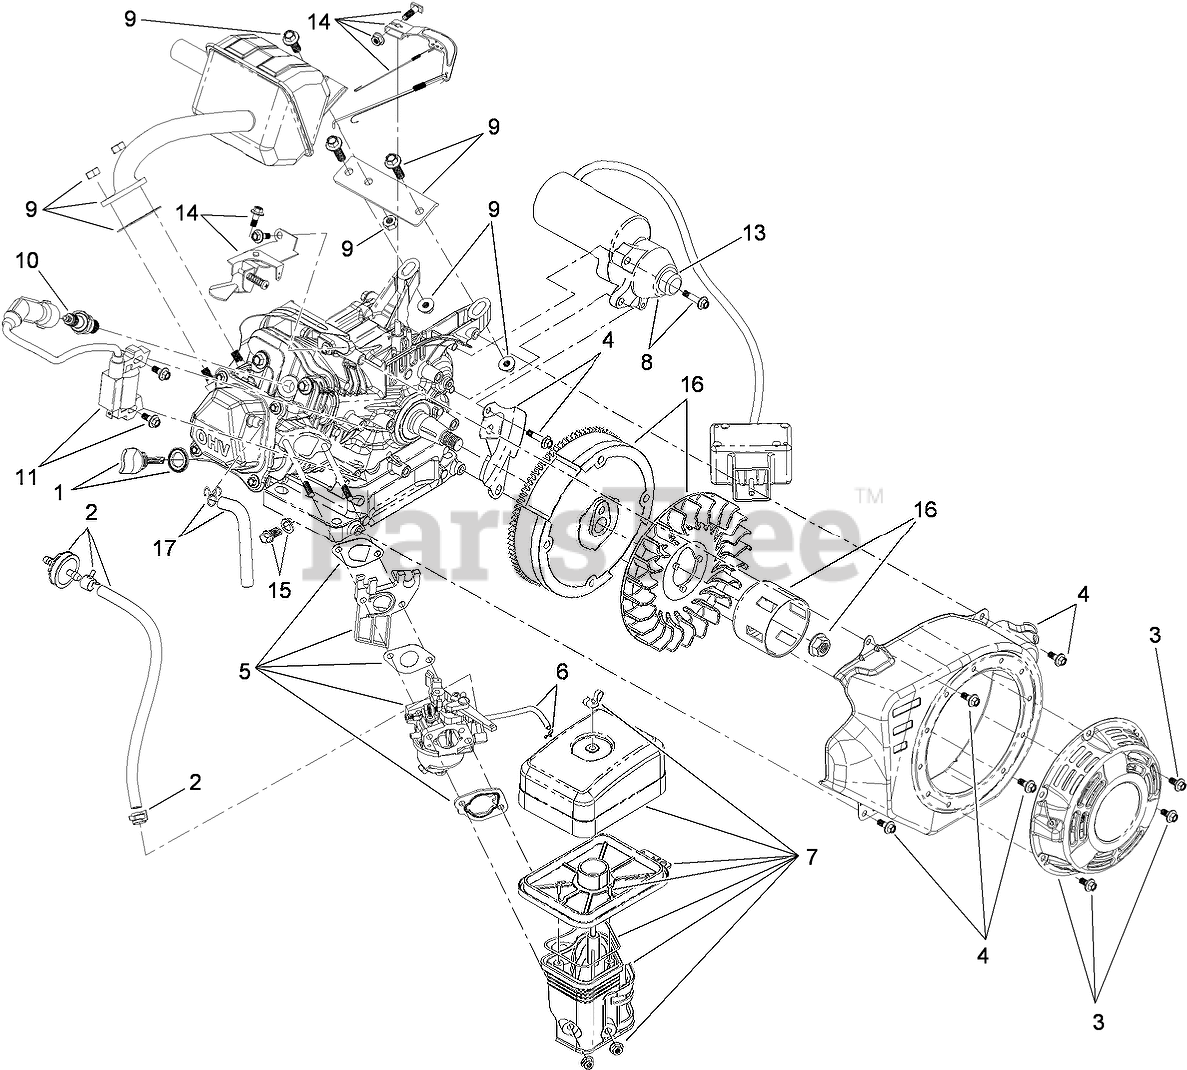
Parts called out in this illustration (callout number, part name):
1	OBS DIPSTICK AND O-RING KIT
2	FUEL LINE KIT
3	RECOIL KIT
4	BLOWER SHROUD KIT
5	CARBURETOR AND FUEL LINE KIT
6	PRIMER LINE KIT
7	HEATER BOX KIT
8	ELECTRIC STARTER KIT
9	MUFFLER KIT
10	PLUG-SPARK
11	IGNITION KIT
13	PINION KIT
14	GOVERNOR KIT
15	DRAIN PLUG KIT
16	FLYWHEEL KIT
17	BREATHER TUBE KIT
